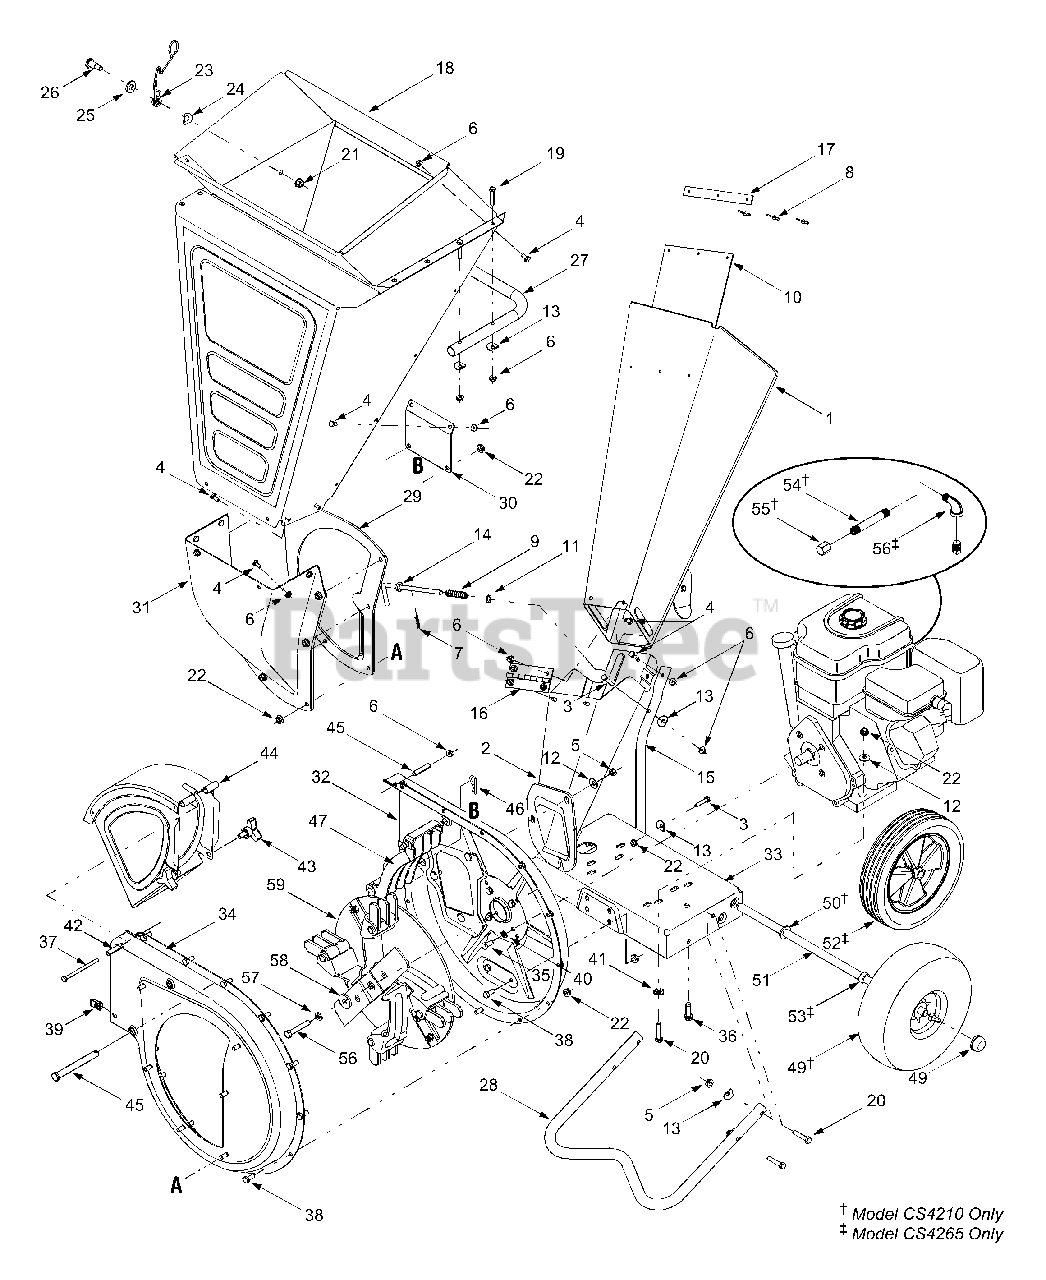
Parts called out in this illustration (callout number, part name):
3	Hex Cap Screw, 1/4-20 x 1.25
4	Hex Cap Screw, 1/4-20 x .5
5	Hex Nut, 5/16-18
6	Hex Lock Nut 1/4-20
7	Cotter Pin
8	Pop Rivet
9	Compression Spring, .531 x 1.75
10	Chute Flap
11	Flat Washer
12	Bell Washer.340 ID x.872 OD
13	Washer,.320 ID x.93 OD
14	Lock Rod
16	Chipper Chute Hinge
17	Chute Flap Strip
19	Hex Cap Screw, 1/4-20 x 1.5
20	Hex Cap Screw, 5/16-18 x 1.50
21	Flange Lock Nut, 3/8-16
22	Flange Lock Nut, 5/16-18
23	Torsion Spring
24	Spring Washer, .50 x 1.0 x .022
25	Flat Washer, .50 x 1.0 x .0125
26	Shoulder Screw, 3/8-16, .50 x .685
35	Hex Cap Screw, 5/16-24 x .75
36	Hex Sems Screw, 3/8-16 x 1.25
37	Hex Cap Screw, 1/4-20 x 3.75
38	Hex Cap Screw, 5/16-18 x..625
39	U-Nut, 5/16-18
40	Lock Washer, 5/16
41	Special Lock Washer, 5/16
42	Hinge Spacer, .265 x .380 x 1.66
43	Knob, 5/16-18
45	Clevis Pin, .50 x 4.62
46	Internal Cotter Pin
47	Shredder Screen
48	Push Cap, 5/8
49	Wheel, 10 x 4 x 4
50	Flat Washer, .625 x 1.0
51	Axle, 22.47" (CS4210)
52	Wheel, 10 x 2.5
53	Spacer, .64 x .88 x .38
54	Oil Drain Pipe
55	Oil Drain End Cap
56	Hex Cap Screw, 3/8-24 x 2.25
57	Lock Washer, 3/8
58	Flat Washer, .406 x 1.25
59	Impeller Assembly
